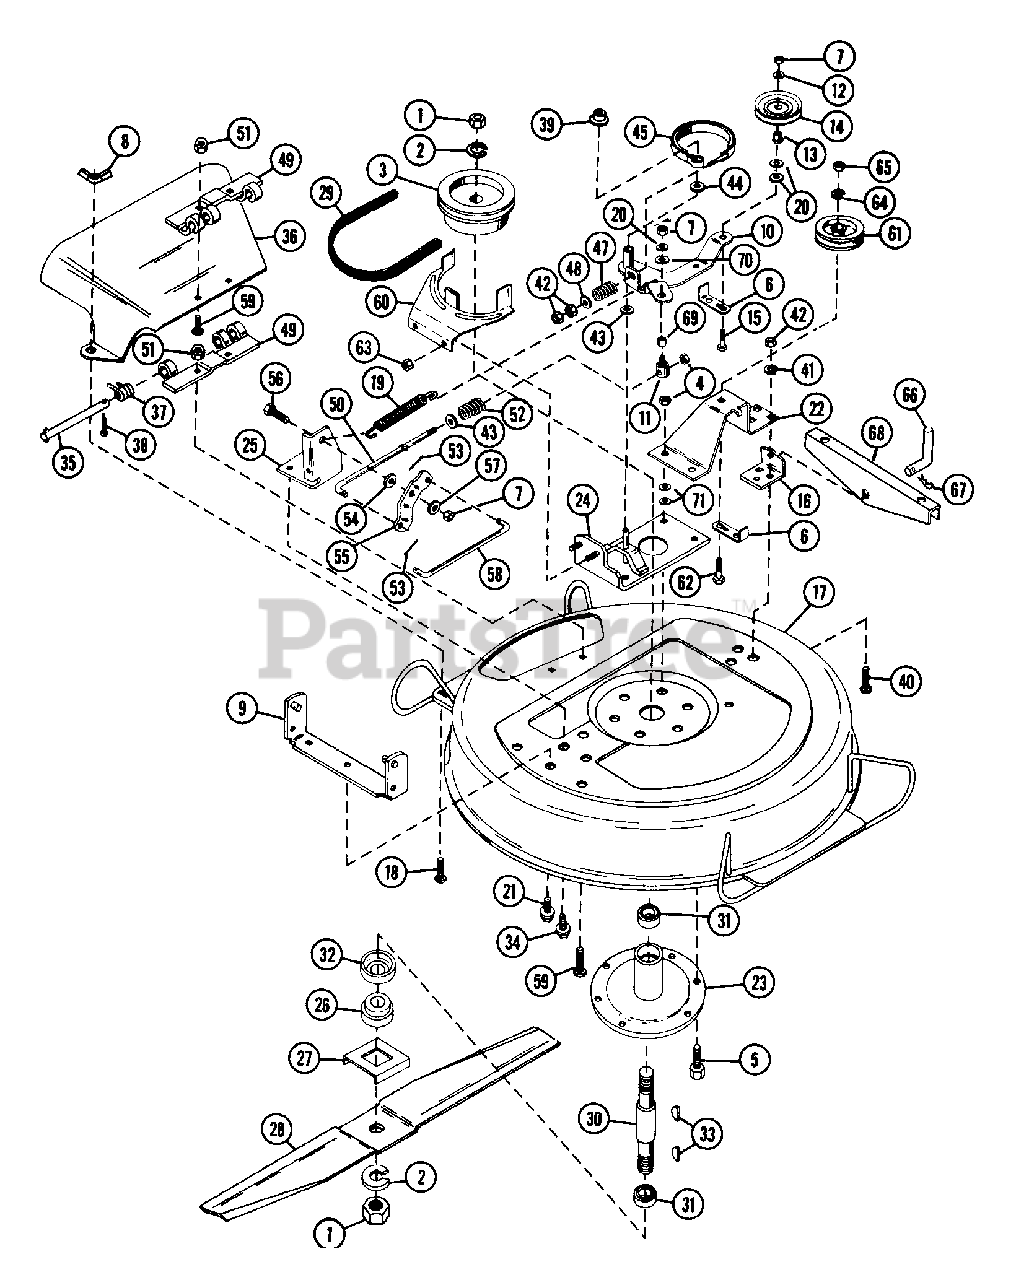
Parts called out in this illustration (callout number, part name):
1	NUT-JAM .75-10 PL
2	WSHR-LK .750X.188 MED PL
3	MOWER SHEAVE
4	NUT-LK-CTR .375-16 GR A PL
5	BLT-HEX .38-16X1.00 PL
6	BELT FINGER
7	NUT-LK .312-18 GR A PL
8	NUT-WING W/INSERT .312 - 18
9	FRONT MOUNTING BRACKET
10	IDLER ARM
11	ROD PIVOT
12	WSHR-FL-STL .323X.625X.062 PL
13	SPCR, BRG .315X.50X.688X.281
14	IDLER
15	BLT-HEX .31-18X1.50 PL GR2
16	REAR MOUNTING BRACKET
17	32 IN MOWER PAN W/ DECALS
18	BLT-RDHDSQNK .31-18X.75 GR5 PL
19	SG-TENS .072X.51X5.31 WLD 25
20	WSHR-FL-STL .38X.875X.083 PL
21	BLT-SCRHFWH .38-16X.50 PL
22	IDLER MOUNT
23	SPINDLE HOUSING
24	PIVOT PLATE
25	DECK PIVOT BRACKET
26	RETAINER HUB
27	BLADE TRAY
28	32 IN MOWER BLADE
30	SPINDLE SHAFT
31	BRG-BALL .750X1.781X.61
32	BEARING SLINGER
33	KEY-WDRF .188X.75X.313 SAE 9
34	BLT-SERHFWH .31-18X.50 PL
35	CLEVIS PIN
36	CHUTE DEFLECTOR
37	SG-TORS .090X.37X.63
38	PIN-COTR .09X.75 PL
39	FASTENER
40	BLT-RDHDSQNK .31-18X.75 GR5 PL
41	WSHR-LK .312X.097 PL HVY
42	NUT-HEX .312-18
43	WSHR-FL-STL .382X.812X.062
44	WSHR-FL-STL .531X1.062X.095 PL
45	BRAKE BAND
46	PIN-COTR .06X.50
47	SG-COMP .072X.687X.75
48	WSHR-FL-STL.344X.688X.065PL
49	HINGE PLATE
50	CLUTCH ROD
51	NUT-LK-CTR .250-20 PL
52	SG-COMP .106X.63X3.42 WLD 90
53	PIN-COTR .12X.75 PL
54	SPACER BUSHING .5 X .32 X .163
56	BLT-HEX .31-18X.88 PL GR2
57	WSHR-FL-STL .344X1.125X.063PL
58	CLUTCH ROD
59	BLT-RDHDSQNK .25-20X.62 PL
60	BELT FINGER
61	IDLER-V 3.06 X .38
62	BLT-HEX .38-16X1.75 PL GR2
63	NUT-FLG. .312-18 PL
64	WSHR-LK .375X.094 MED PL
65	NUT-HEX .375-16
66	CLEVIS PIN
67	PIN-HAIR INT .08X.38X1.42 YWZC
68	SWIVEL BRACKET
69	SPACER BUSHING .5 X .32 X .21
70	WAVE WASHER .531X.781X.125FH
71	WSHR-FL-STL .438X1.0X.083 PL
